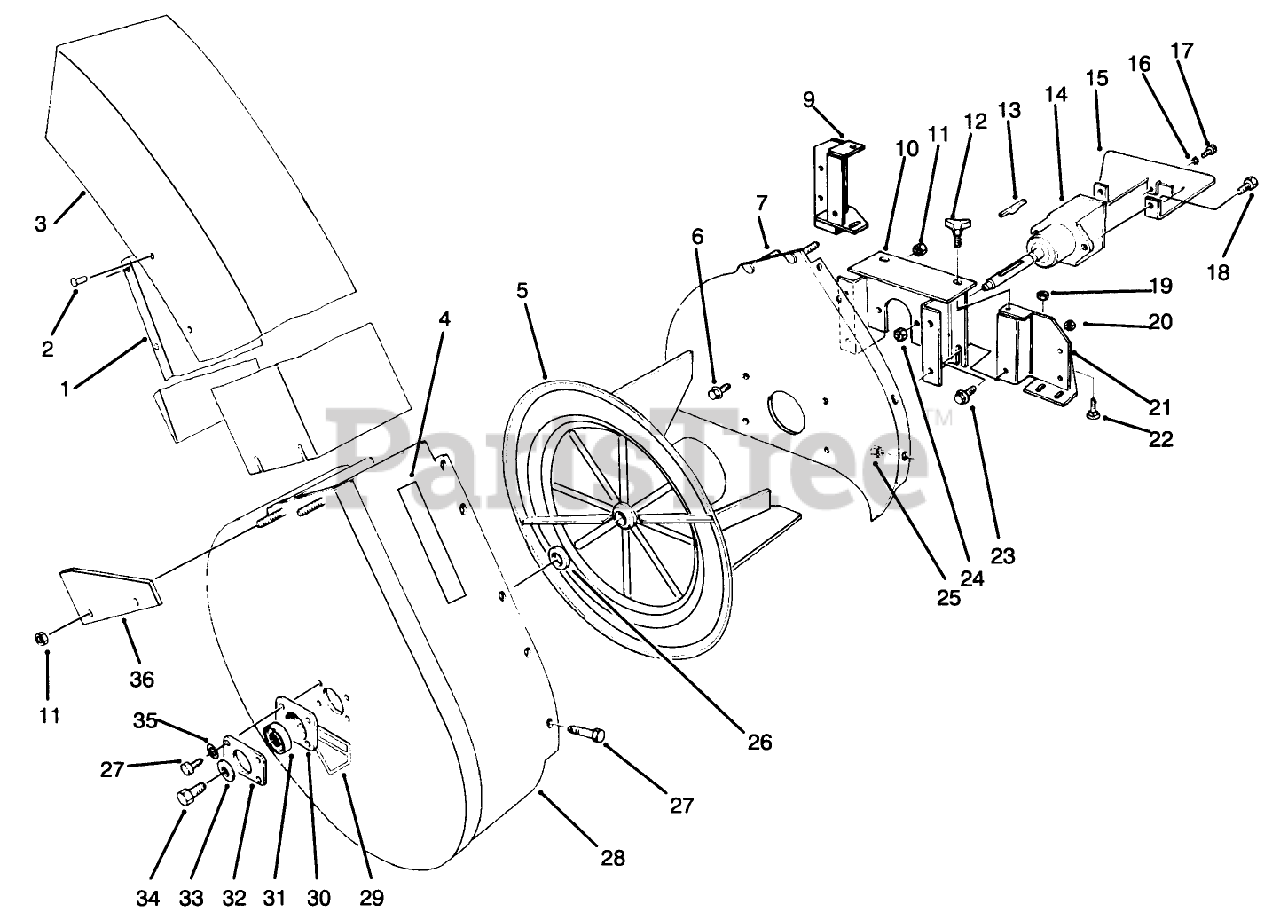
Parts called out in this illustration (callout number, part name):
1	Deflector
3	Chute Assembly (Incl. Ref. #1 & 2)
4	DECAL
5	Impeller
6	SCREW-HHF
7	Mounting Plate
9	L/H BLOWER MT/NUT ASM
10	Blower Mount
11	NUT-LOCK, NI
14	Asm-Gear Box
15	Cover-Gear Box
16	WASHER-LOCK, EXT
18	SCREW-HH
19	NUT-KEPS
20	NUT-JAM
21	RH BLWR MT BRKT WA
22	SCREW-HHF
23	SCREW-CARR
24	NUT-LOCK, NI
25	NUT-LOCK, NI
26	SPACER-BEARING
27	SCREW-HH
28	Housing-Blower (Incl. Ref. #4 & 29)
29	DECAL-DANGER
30	CUP-BEARING
31	BEARING-BALL
32	Cover-Plate
33	SPACER
34	SCREW-HH, LOCK
35	WASHER-LOCK
36	Bracket
